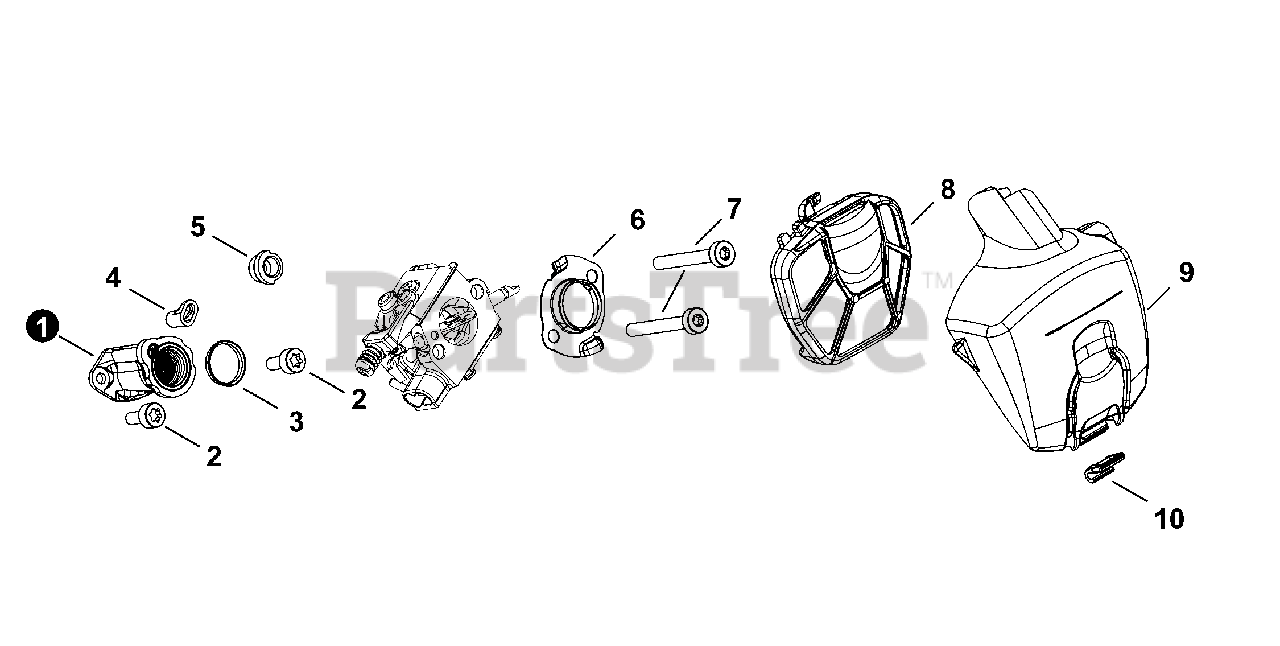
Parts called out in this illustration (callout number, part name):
1	BELLOWS, INTAKE
2	BOLT, TORX 4×10
3	COLLAR 14
4	COLLAR 3
5	PLUG
6	ELBOW, CARBURETOR
7	BOLT, TORX 5×40
8	FILTER ASSY, AIR - FABRIC MESH
9	COVER, AIR FILTER
10	RETAINER, AIR FILTER
